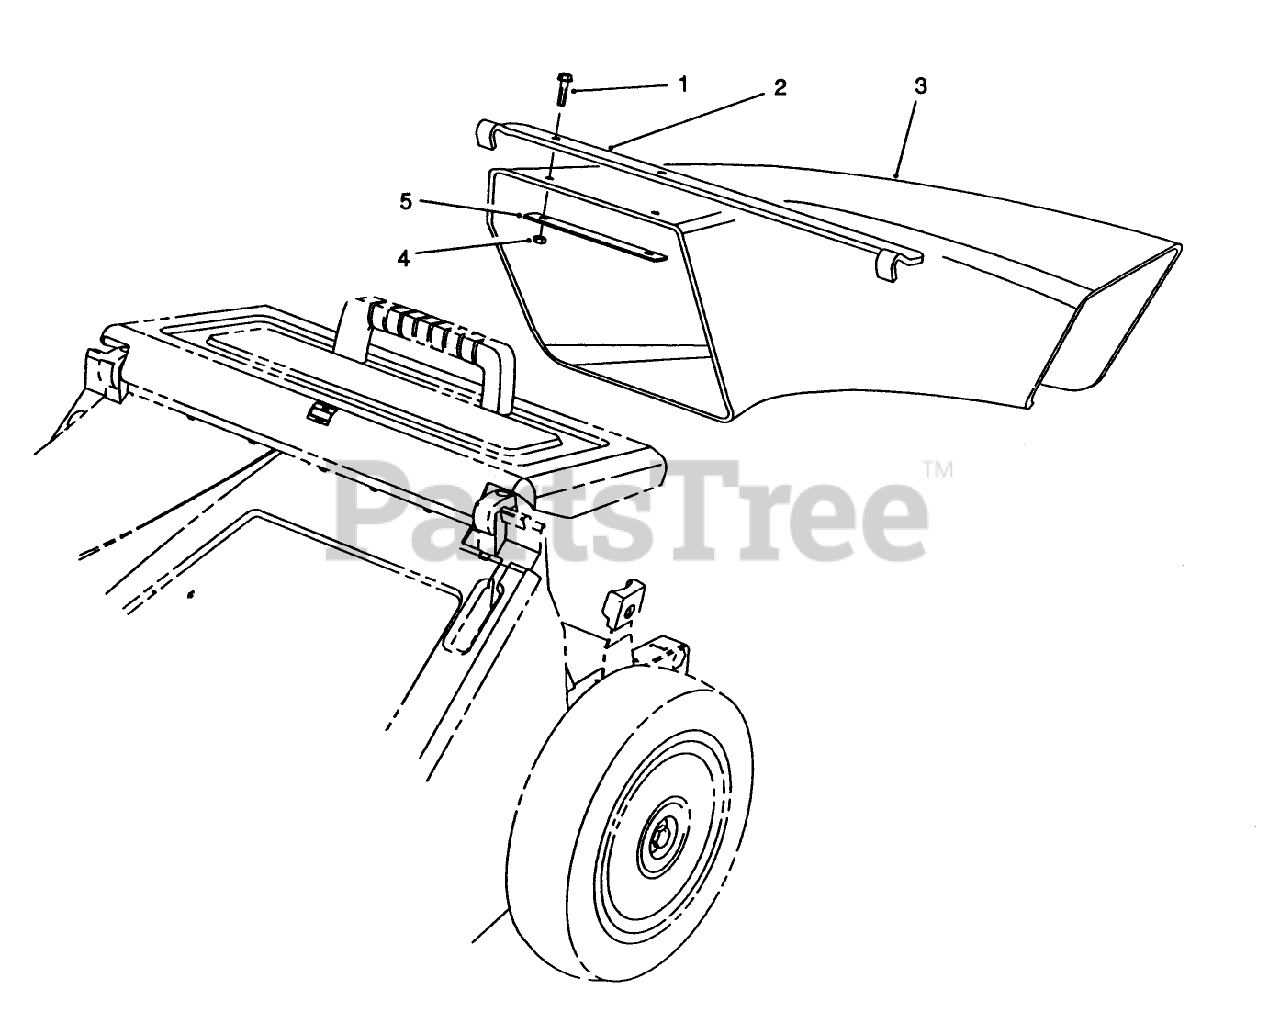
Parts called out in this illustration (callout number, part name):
1	SCREW-HWH
2	CHUTE HANGER BRACKET*
4	NUT-LOCK, NI
